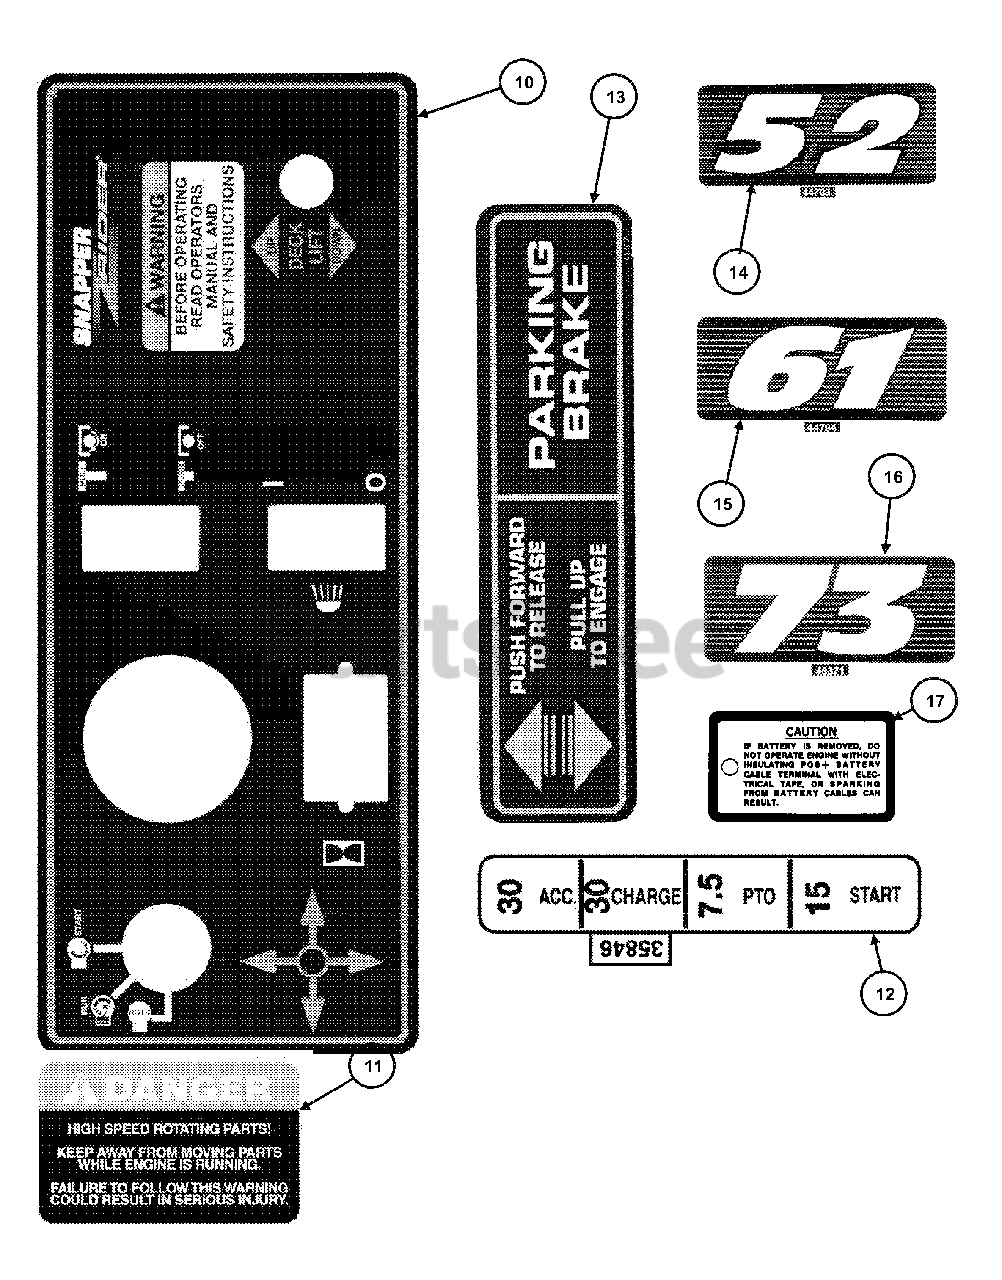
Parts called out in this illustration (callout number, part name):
10	DECAL, Control Panel
11	DECAL, Danger
12	DECAL, Fuse
13	DECAL, Parking Brake
14	DECAL, 52" Deck
15	DECAL, 61" Deck
16	DECAL, 73" Deck
17	DECAL, Caution Tag
